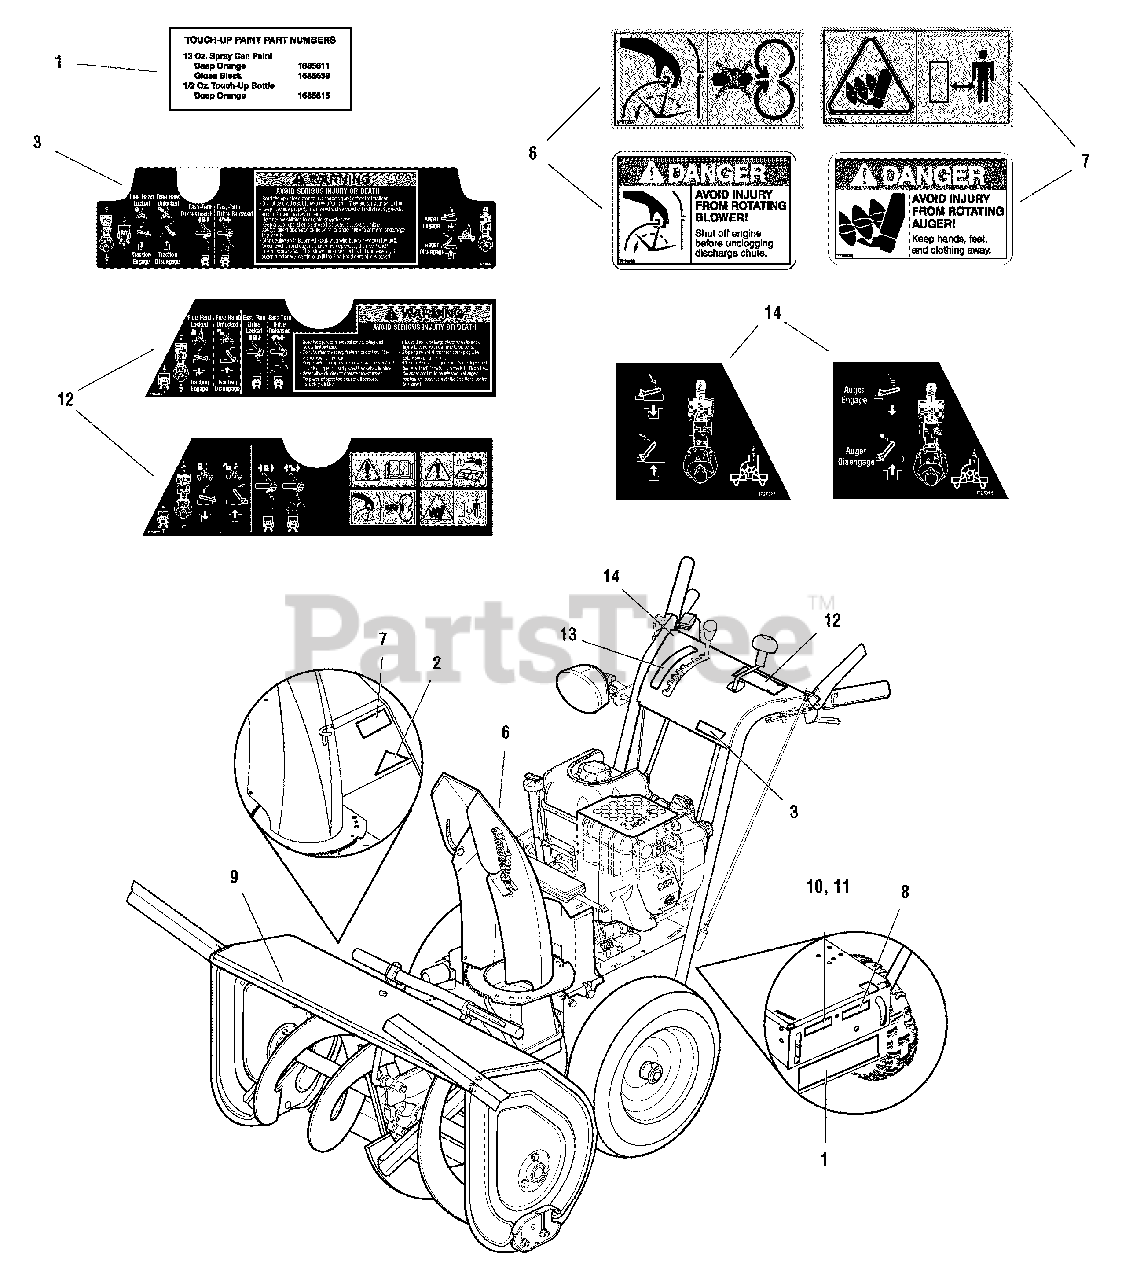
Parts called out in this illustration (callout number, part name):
1	DECAL, Touch Up Paint, Orange, Black, Red
3	DECAL, Dashboard Snapper
6	DECAL, DANGER Auger - Use Snow Stick
7	DECAL, Danger Avoid Injury from Auger
8	* DECAL, Patent Snowthrower
9	DECAL, Snapper Stripe 1738XL
12	DECAL, Instruction w/EZ Turn L.H.
12	DECAL, Tube Handle L.H.
13	DECAL, Shift 1,2,3,4,5,6 R1 R2
14	DECAL, Instruction, Auger Control
14	DECAL, Tube Handle R.H.
